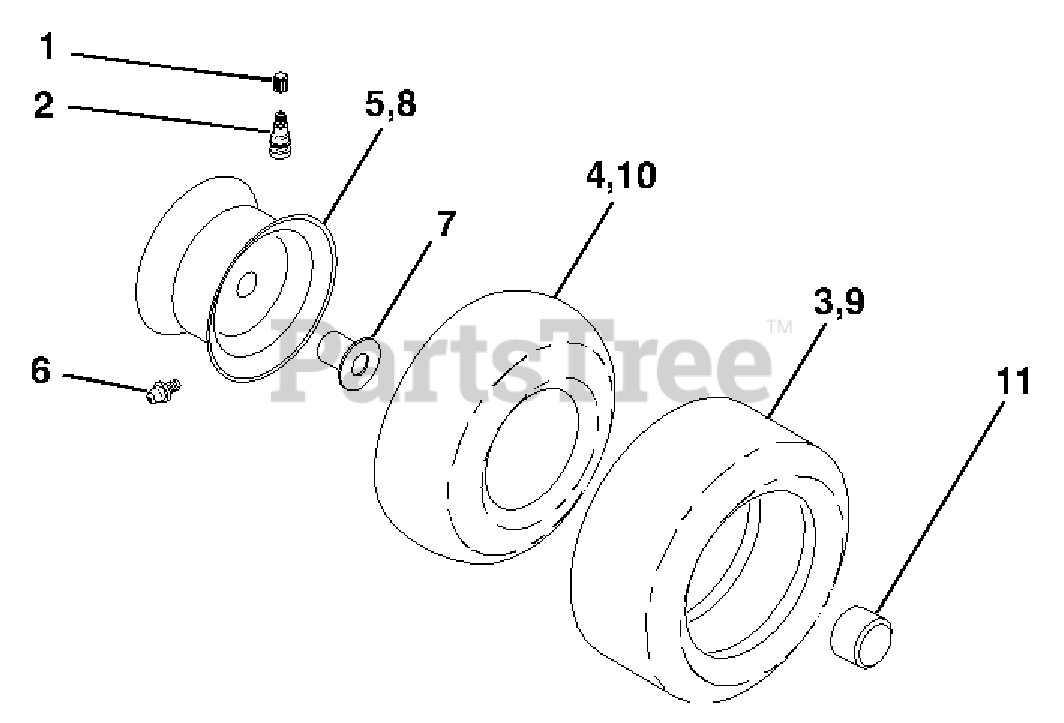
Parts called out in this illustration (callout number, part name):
1	Cap Valve Tire
2	Stem Valve
3	Tire F T 15 x 6 0- 6 Service
4	Tube Front (Service Item Only)
5	Rim Asm 6" front Service
6	Fitting Grease (Front Wheel Only)
7	Bearing Flange (Front Wheel Only)
8	Rim Asm 8" rear Service
9	Tire R T 20 x 8-8 Service
10	Tube Rear (Service Item Only)
11	Cap Axle Blk 1 50 x 1 00
